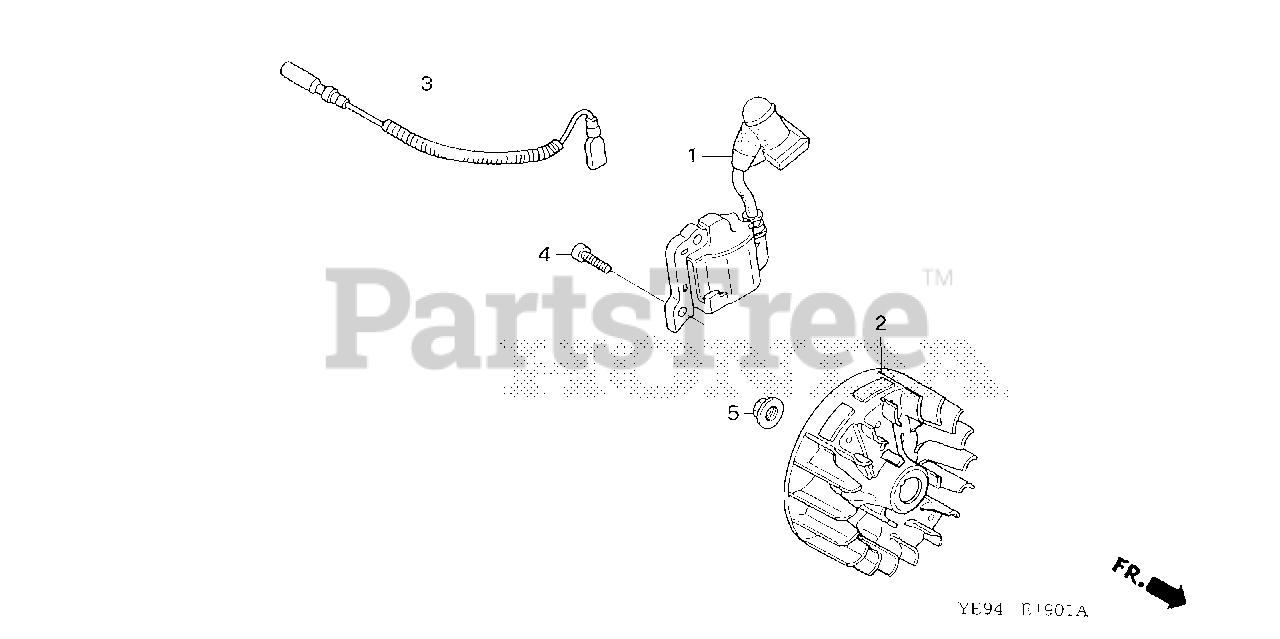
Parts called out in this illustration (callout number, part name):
1	COIL ASSY., IGNITION
2	FLYWHEEL
3	WIRE, STOP SWITCH
4	BOLT, SOCKET (4X14)
5	NUT, FLANGE (7MM)
